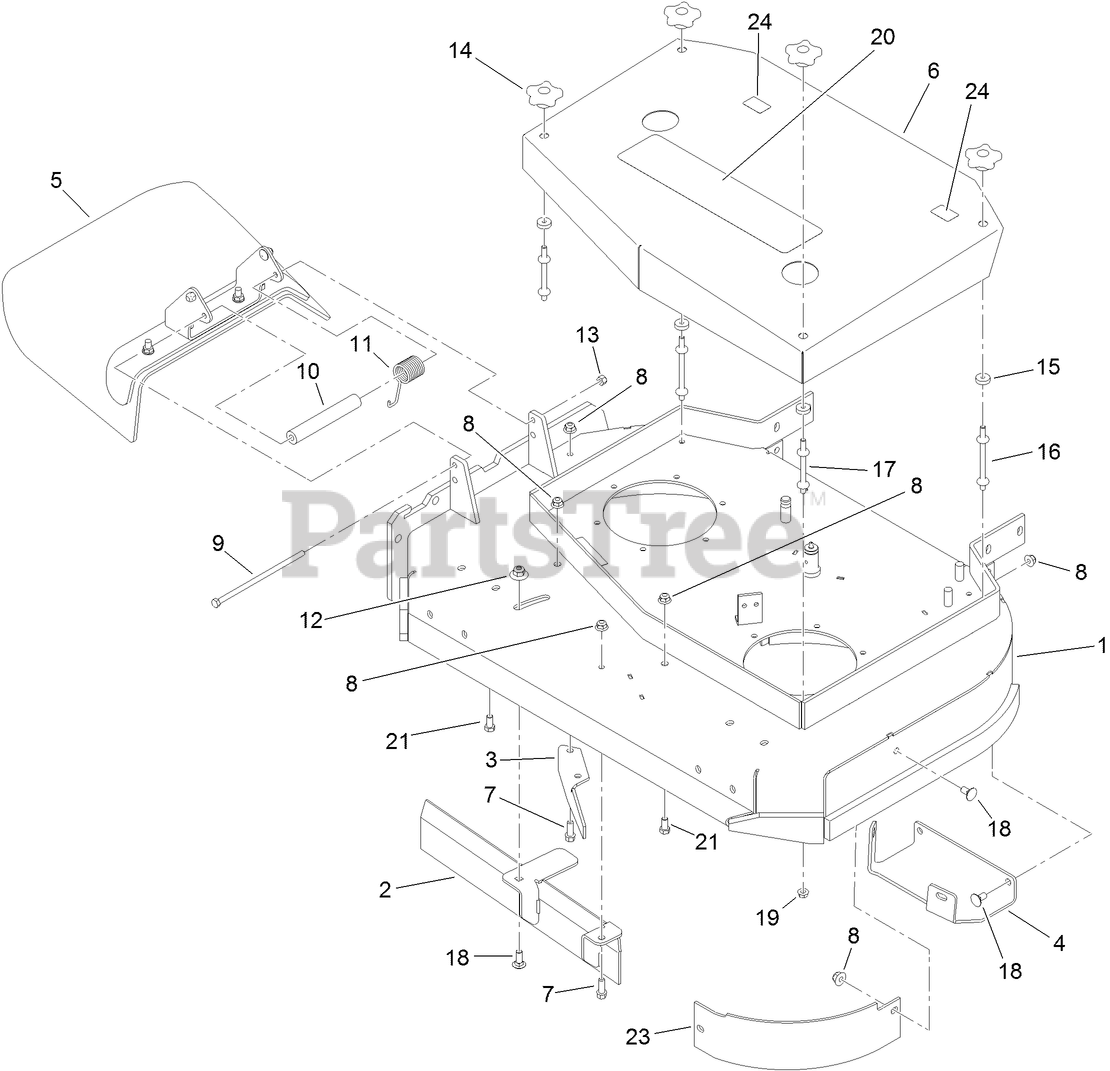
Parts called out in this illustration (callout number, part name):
1	DECK ASM
3	BAFFLE-DISCHARGE
4	PLATE-SKID
5	DEFLECTOR ASM
6	COVER-DECK
7	SCREW-HWH
8	NUT-HF, NI
9	SCREW-HH
10	SPACER
11	SPRING-TORSION
12	NUT-FLANGE, NI
13	NUT-LOCK, NI
14	KNOB-HANDLE
15	WASHER
16	STUD-SHIELD, BELT (LONG)
17	STUD-SHIELD, BELT (SHORT)
18	BOLT-CARR
19	NUT-HF
21	SCREW-HH
23	BAFFLE-FRONT, LH
24	DECAL-CAUTION
